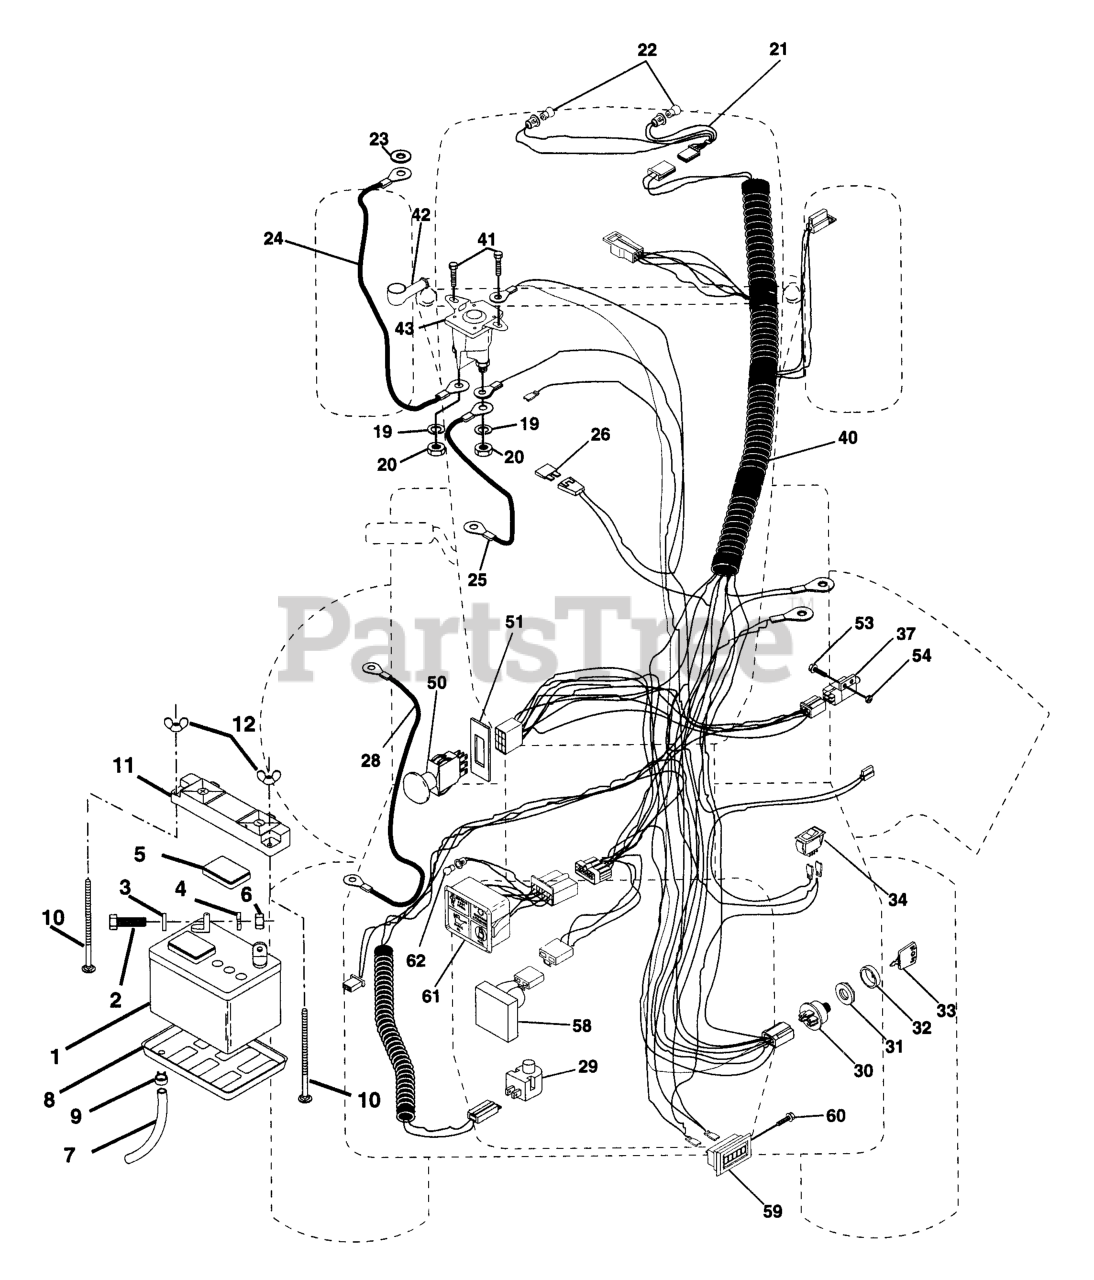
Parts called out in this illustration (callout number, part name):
1	BATTERY
2	BOLT.HEX.1/4.X.3/4.DICHROMATE
3	LOCKWASHER
4	WASHER
5	CAP BATTERY NLA
6	NUT
7	PLASTIC TUBE
8	BATTERY TRAY T
9	HOSE CLAMP T
11	TERMINAL GRD YTV
12	WING NUT
19	LOCKWASHER
20	NUT
21	HARNESS LIGHT SOC
23	Washer, Lock Int. Tooth 1/4
24	BATTERY CABLE GT
25	CABLE-BATTERY YTV
28	CABLE T
29	RP.SWITCH.PLUNGER.NC.GRAY
30	IGNITION SWITCH
31	NUT, IGNITION
32	COVER SWITCH KEY
33	KEY MLD GEN DELTA
37	SWITCH-INTER. GT
40	IGNITION HARNESS
41	SCREW
42	TERMINAL COVER
43	SOLENOID
50	SWITCH-PTO
51	FRAME RETAINING RING
53	SCREW **
54	Nut Keps #10-32
58	SENSOR LOW VOLTAGE
59	HOUR METER T
60	Screw #10-24 x 1/2
61	LIGHT PACKAGE
62	BULB LIGHT T
